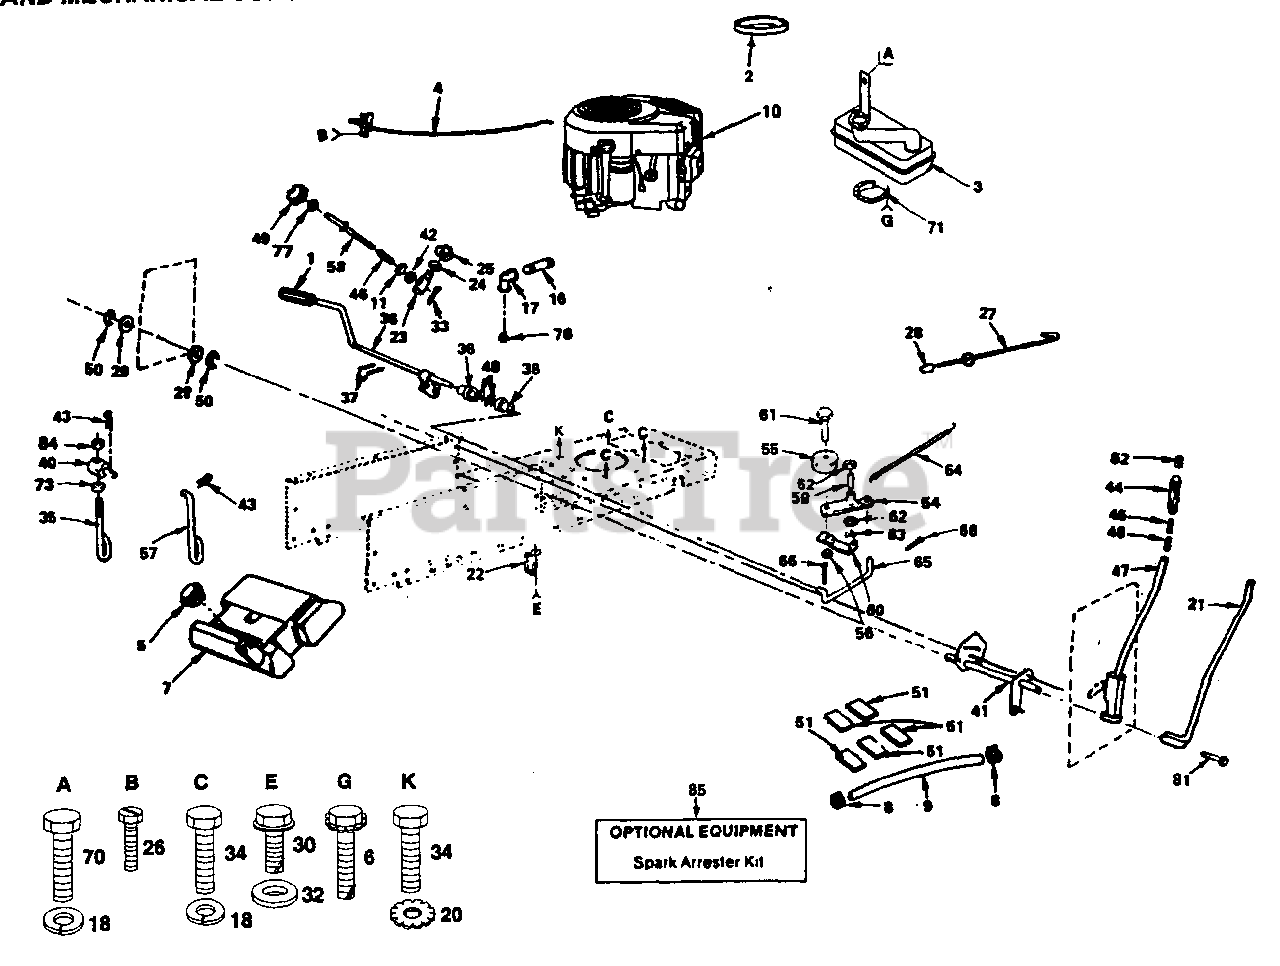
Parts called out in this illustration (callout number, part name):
1	Cover, Pedal
4	Control, Throttle
5	Cap, Fuel
6	Screw, Spider Lock, Hex Head #8 x 1/2 AB
9	Line, Fuel
10	Engine, 14 HP Kohler, Model No. CV145-1436
11	Washer 13/32 x 5/8 x 16 Gauge
16	Pipe Nipple, Standard
17	90ø Elbow 3/8 NPT
18	Washer, Lock Heavy Helical Spring
20	Washer, Lock External Tooth
21	Rod Assembly, Lever
22	Retainer, Belt, Chassis, L.H.
23	Trunnion, Stop, Depth
24	Washer 15/32 x 3/4 x 16 Gauge
26	Screw, Hex Thread Cut 1/4-20 x 5/8
27	Rod, Brake, Park
29	Washer 29/32 x 1-1/4 x 16 Gauge
30	Screw, Hex Washer Thread Rolling 3/8-16 x 3/4
32	Washer 13/32 x 1-3/16 x 12 Gauge
33	Pin, Cotter 3/32 x 1/2
34	Screw M8 x 1.25 x 25 mm
35	Lift, Link, Adjustable
36	Shaft, Pedal, Foot
37	Roll Pin 3/16 x 1
38	Bearing, Nylon
40	Trunnion, Lift
41	Shaft Assembly, Lift
42	Nut, Hex, Special
43	Retainer, Spring
44	Grip, Handle
45	Plunger, Lever Lift
46	Spring
47	Lever Assembly, Hand Kit
48	Washer 21/32 x 1 x 16 Gauge
49	Handle, Adjust, Lift
52	Button, Plunger
54	Arm Assembly, Idler
55	Pulley, Idler
56	Nut, Crownlock 3/8-16
58	Rod, Adjust, Lift
60	Retainer, Belt
61	Bolt, Hex 3/8-16 x 1-1/2
62	Washer, Hardened
64	Spring, Return, Clutch
65	Link, Clutch
66	Pin, Cotter 1/8 x 3/4
70	Bolt, Hex Head 5/16-18 UNC x 1/2
71	Deflector, Muffler
73	Nut, Hex, Jam 7/16-20
77	Nut, Hex, Jam 3/8-16
81	Bolt, Hex 3/8-16 x 1-1/2
84	Nut, Crownlock 7/16-20
85	Spark Arrester Kit
